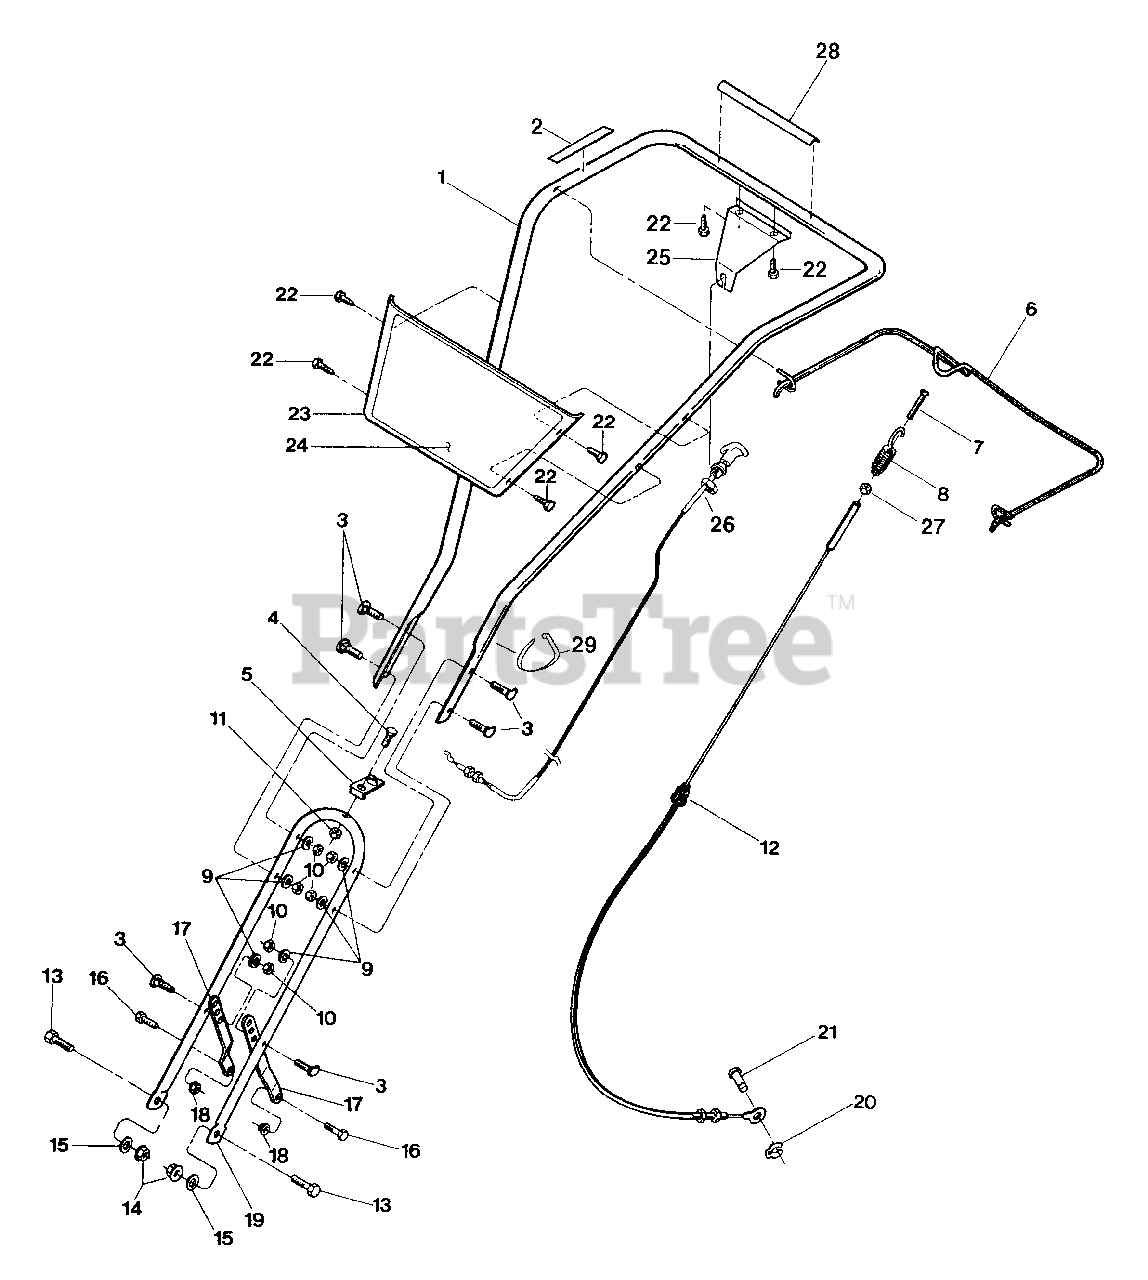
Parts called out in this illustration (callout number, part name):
1	Upper Handlebar
2	Decal, Forward Clutch Bail
3	Hex Hd Screw, 5/16-18 x 1-1/2
4	Hex Hd. Screw, 1/4-20 x 1-1/4
5	Bracket, Forward Clutch Cable
6	Bail, Forward Clutch
7	Screw, #10-24 x 2
8	Spring, Forward Clutch
9	Lock Washer, 5/16
10	Hex Lock Nut, 5/16-18
11	Hex Lock Nut, 1/4-20
12	Cable Ass'y, Forward Clutch
13	Hex Hd. Screw, 3/8-16 x 3/4
14	Hex Lock Nut, 3/8-16
15	Flat Washer, 3/8
16	Hex Hd Screw, 5/16-18 x 3/4
17	Handlebar Support
18	Hex Lock Nut, 5/16-18
19	Lower Handlebar
20	Klip Ring
21	Clevis Pin
22	Hex Screw, 1/4-20 x 1/2, Self-Tap
24	Decal, Model Name/Logo
25	Bracket, Reverse Clutch Cable
26	Cable Ass'y, Reverse Clutch
27	Hex Nut, #10-24
28	Decal, Reverse Drive Control
29	Cable Tie
